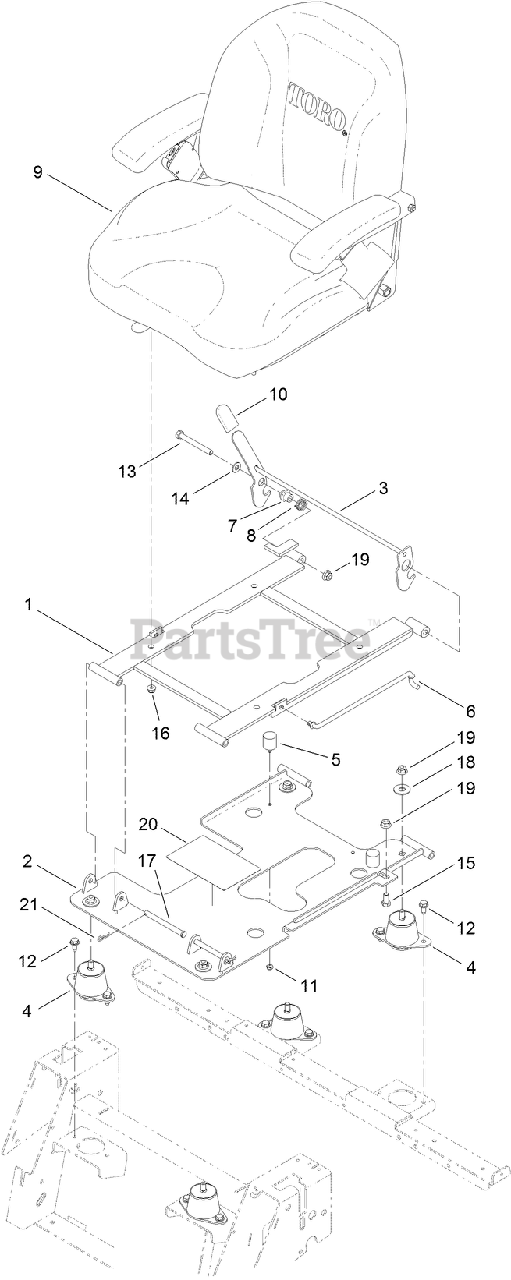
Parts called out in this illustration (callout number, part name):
1	SEAT PAN ASM
2	SEAT BASE ASM
3	LATCH ASM
4	ISOLATOR-SEAT
5	BUMPER
6	ROD-PROP
7	BUSHING-LATCH, SEAT
8	SPRING-TORSION
9	SEAT ASM
10	GRIP-LEVER
11	NUT-LOCK, NI
12	SCREW-HWHTF
13	SCREW-HH
14	WASHER-FLAT
15	SCREW-HH
16	NUT-HF, NI
17	PIN-CLEVIS
18	WASHER-FLAT
19	NUT-HF, NI
20	DECAL-MAINTENANCE
21	PIN-COTTER
